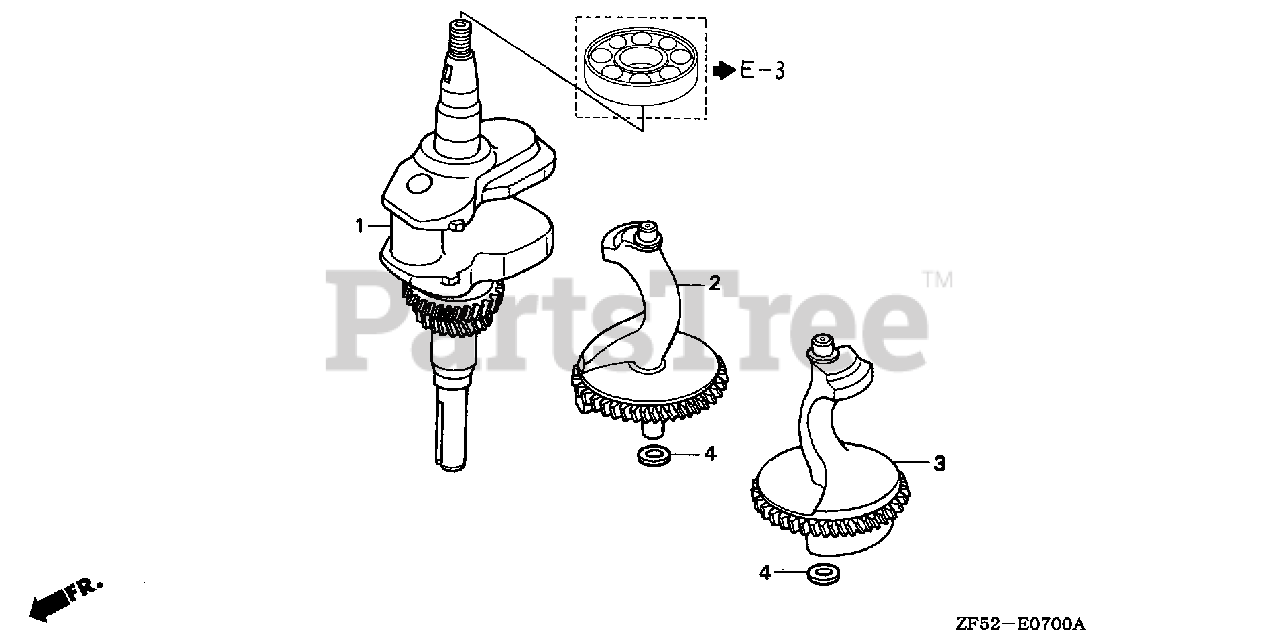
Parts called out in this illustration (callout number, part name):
1	CRANKSHAFT
2	WEIGHT A, BALANCER
3	WEIGHT B, BALANCER
4	WASHER, THRUST (15MM)
